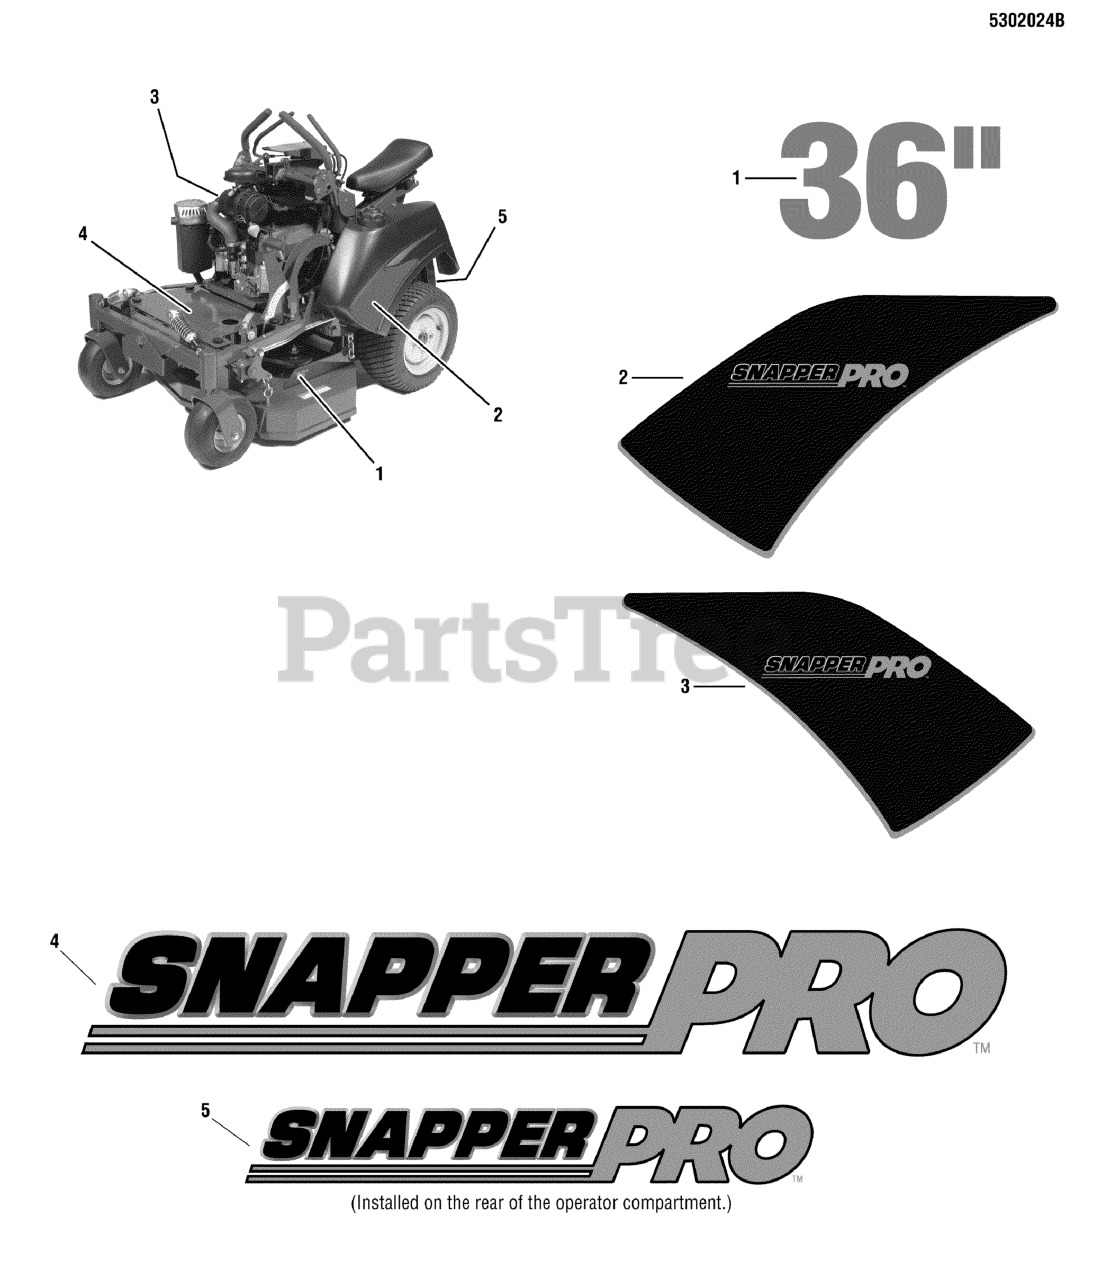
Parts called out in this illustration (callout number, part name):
1	DECAL, 36
2	DECAL, BADGE, SNP, LH
3	DECAL, BADGE, SNP, RH
4	DECAL, SNAPPER PRO, FRONT
5	DECAL, SNAPPER PRO, 12.87 X 1.83
